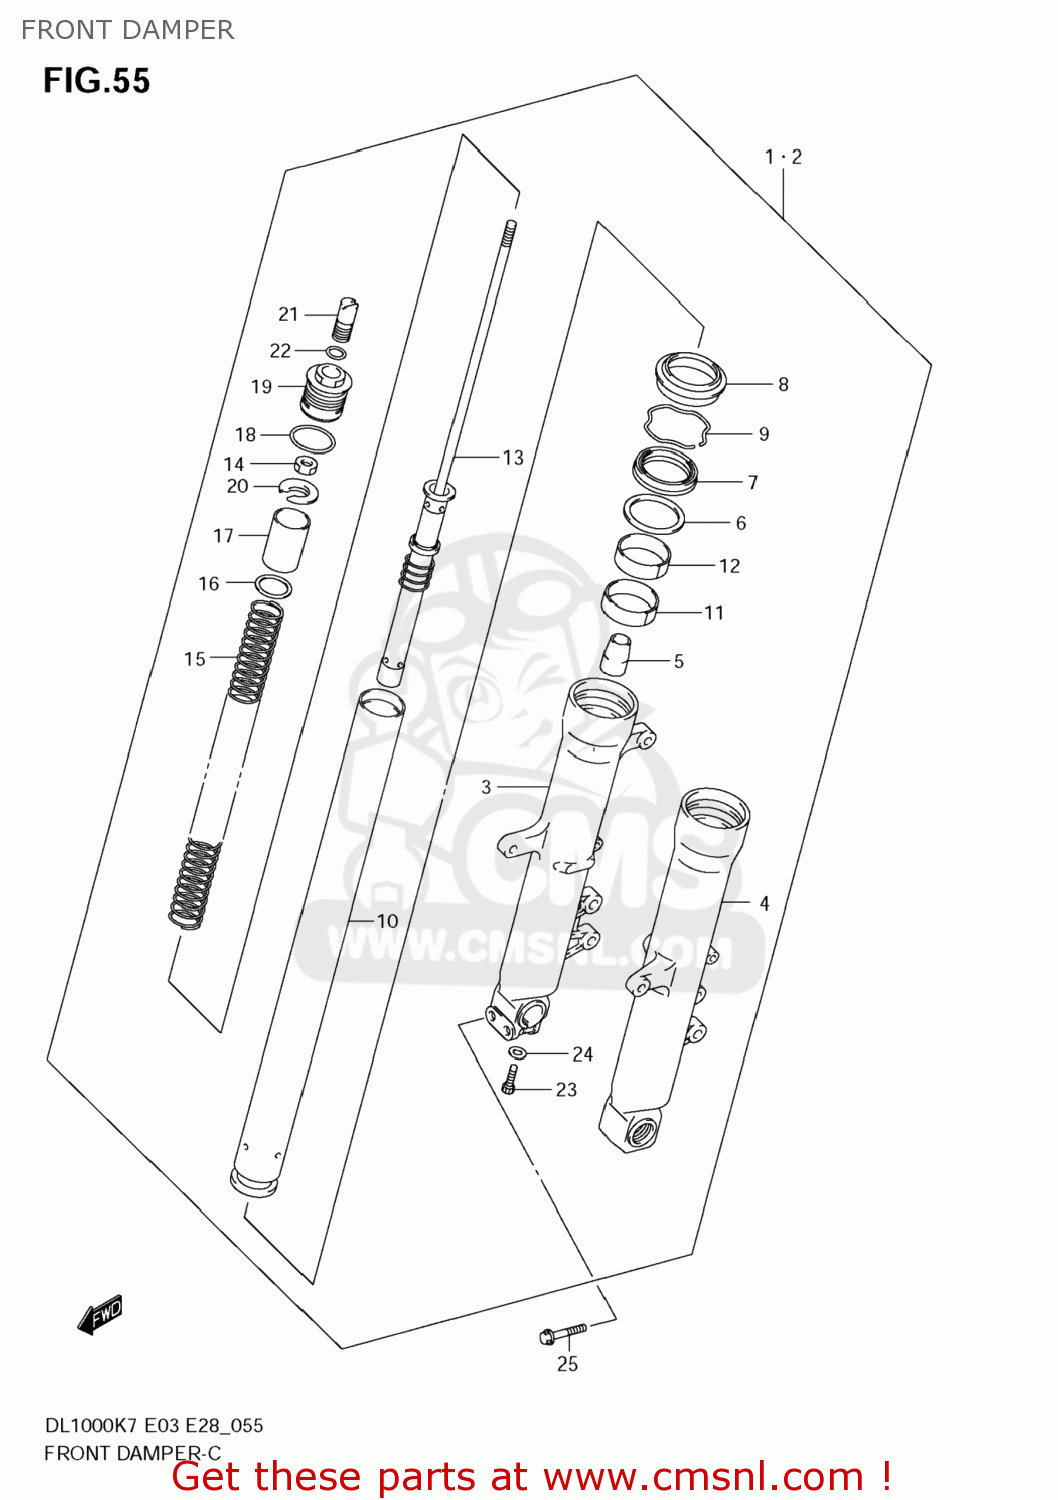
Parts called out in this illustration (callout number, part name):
1	DAMPER ASSY,FR FORK,R
2	DAMPER ASSY,FR FORK,L
3	TUBE,OUTER,R
4	TUBE,OUTER,L
5	PIECE,OIL LOCK
6	SPACER,SEAL
7	SEAL,OIL
8	SEAL,DUST
9	CIRCLIP,FORK OIL SEAL
10	TUBE,INNER
11	BUSH,SLIDE
12	BUSH,GUIDE
13	ROD,FR DAMPER
14	NUT
15	SPRING,FR
16	SEAT,SPRING LWR
17	COLLAR,SPRING(32.9X34X50)
18	O RING
19	BOLT,FORK
20	SEAT,SPRING UPR
21	ADJUSTER,SPRING
22	O RING(D:2.5,ID:13.8)
23	BOLT(8X27)
24	GASKET (NAS)
25	BOLT
